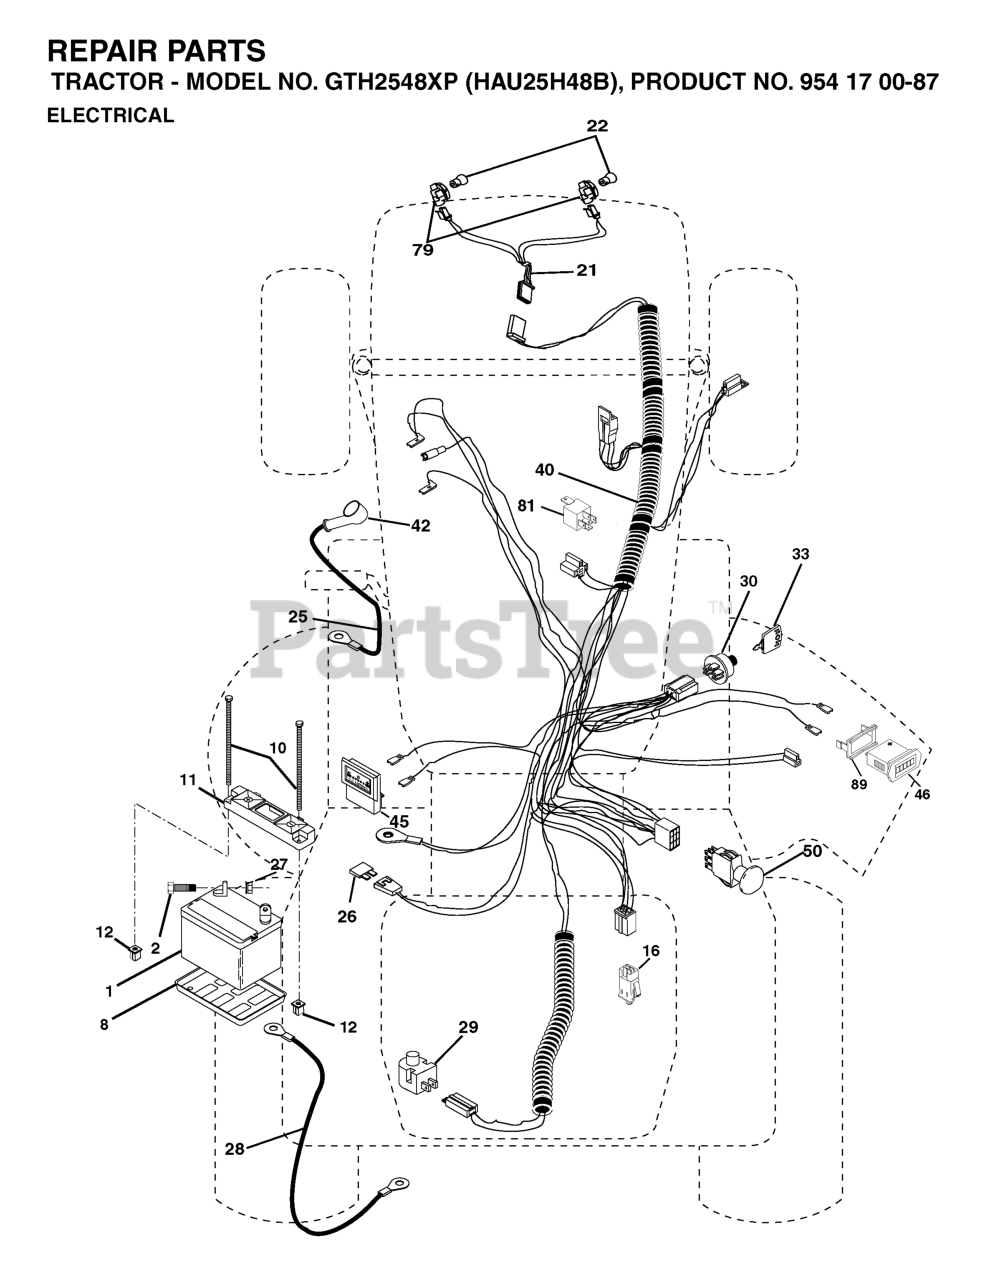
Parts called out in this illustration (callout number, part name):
1	BATTERY 12V .35 AMP
2	BOLT.HEX.1/4.X.3/4.DICHROMATE
8	BATTERY TRAY T
10	BOLT 1/4-20 X 7.5
11	BATTERY HOLDDOWN FRONT MOUNT
12	NUT, PUSH NYLON 1/4" BATTERY
16	SWITCH INTERLOOK PUSH-IN
21	HARNESS.W/LIGHT SOCKET
25	CABLE.4GA.RED.W/16GA.RED.WIRE
27	NUT
28	CABLE, GROUND
29	RP.SWITCH.PLUNGER.NC.GRAY
30	IGNITION SWITCH
33	KEY MLD GEN DELTA
42	COVER.TERMINAL.RED
46	HOUR METER
50	RP.PTO.SWITCH.8 TERMINAL.BLACK
79	BULB HOLDER ASM.
81	RELAY.ASSY.T
89	BRACKET SNAP-IN HOURMETER
